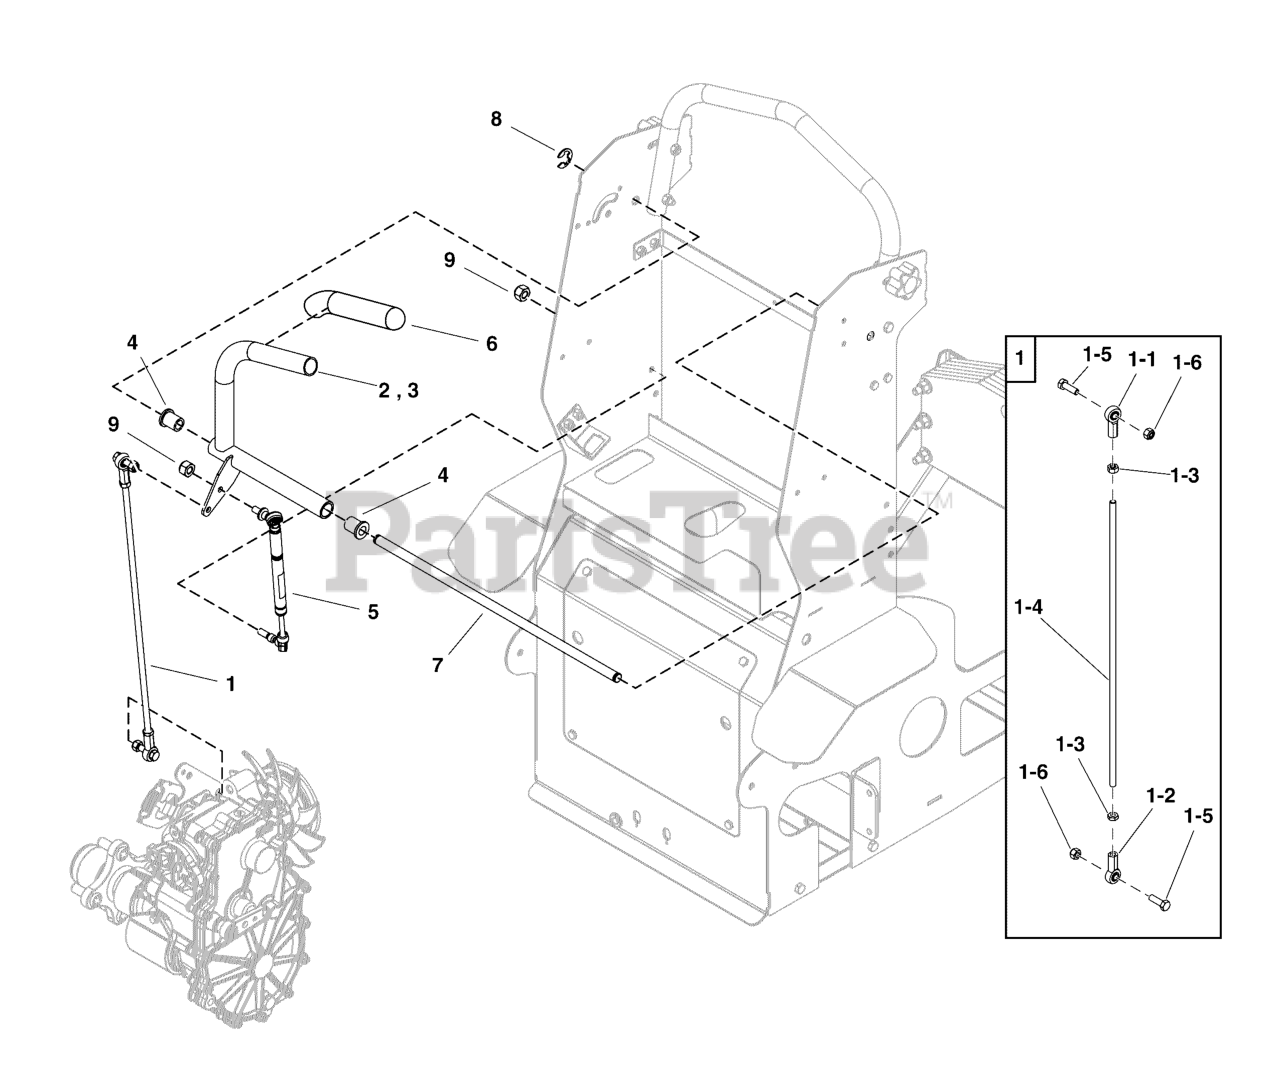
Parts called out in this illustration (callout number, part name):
1	ASM, MOTION CONTROL ROD
1-1	ROD END, FEMALE 5/16-24 LH ZP PTFE RACE
1-2	ROD END, FEMALE 5/16-24 RH ZP PTFE RACE
1-3	NUT-HEX, JAM .3125"-24 SS188
1-4	ROD, CONTROL 5/16-24 THD X 18.50" MZ
1-5	SCR-CAP, HEX .3125"-18 X 1.000" SS188
1-6	NUT-HEX-NYLK, 0.3125"-18 SS188
2	WELD, LH CONTROL ARM
3	WELD, RH CONTROL ARM
4	BUSHING, FLANGE 1/2 ID X 3/4 OD X 1 LG
5	DAMPER, CONTROL ARM
6	GRIP, MOTION CONTROL
7	ROD, .500" OD MOTION CONTROL
8	E-RING, 0.500" SHAFT YZ
9	NUT-HEX-NYLK, 0.3125"-18 SS188
